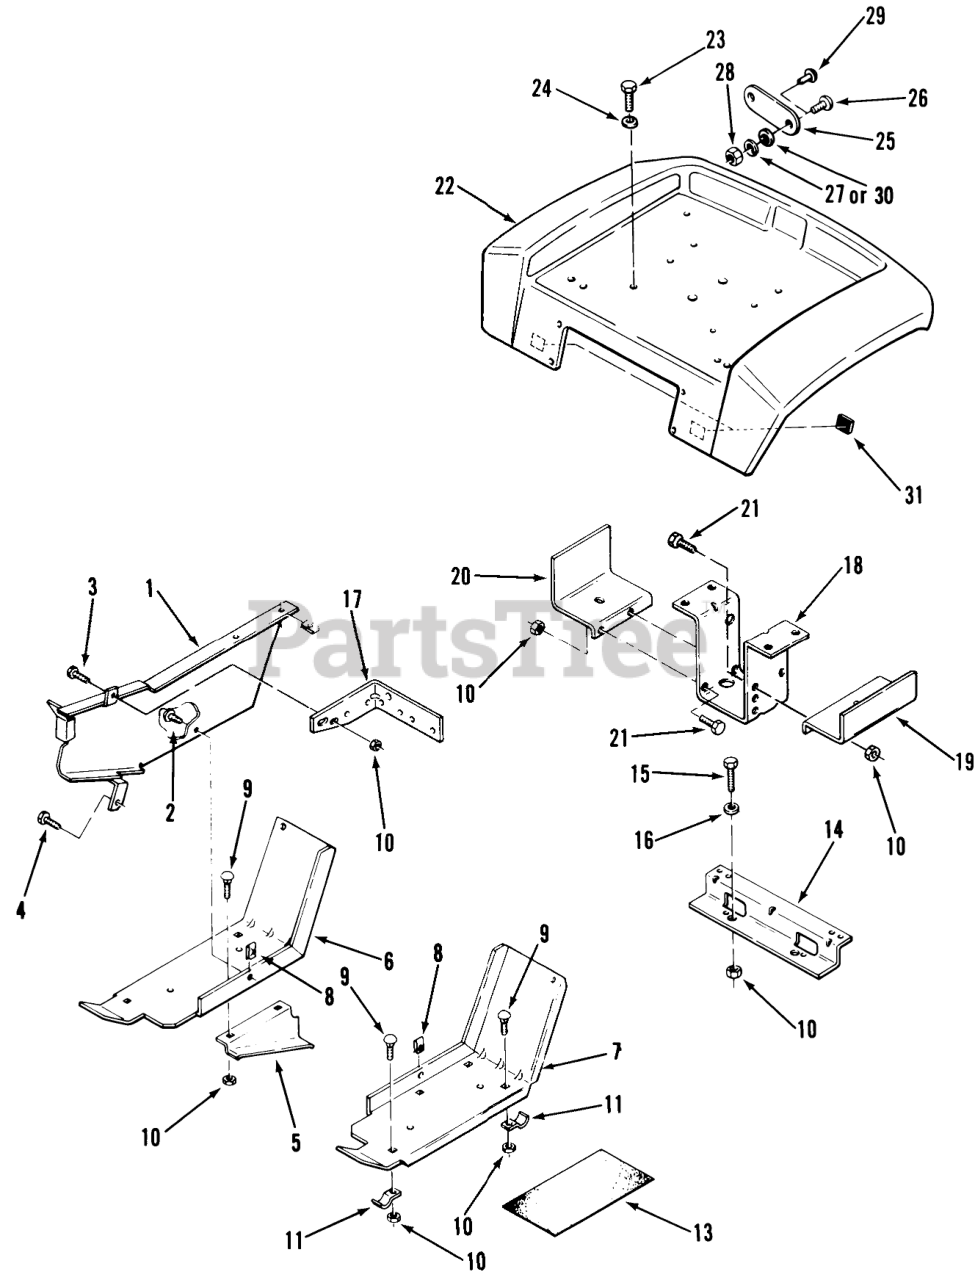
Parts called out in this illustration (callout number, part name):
1	Belt Guard
1	ASSY-BELT GUARD 8 R
2	Screw
3	Bolt
4	SCREW
5	GUID-LOWER BLTR
6	Footrest-RH
7	FOOTREST LH R
9	CARRIAGE BOLT -4
10	Nut
11	BRACKET
13	PAD-FOOTREST
14	BRACKET-FENDER B
15	Bolt
16	WASHER 5/16 SAE
17	BRACKET-BELTB
18	Bracket-Fender Support
19	Fuel Tank Support LH
20	Support-FueITank RH
21	Bolt
22	Fender
23	Bolt
24	WASHER 5/16 SAE
24	Collar
25	Reflector
26	Screw
27	Lockwasher
28	Nut
29	Poprivet
30	WASHER
31	BUMPER
